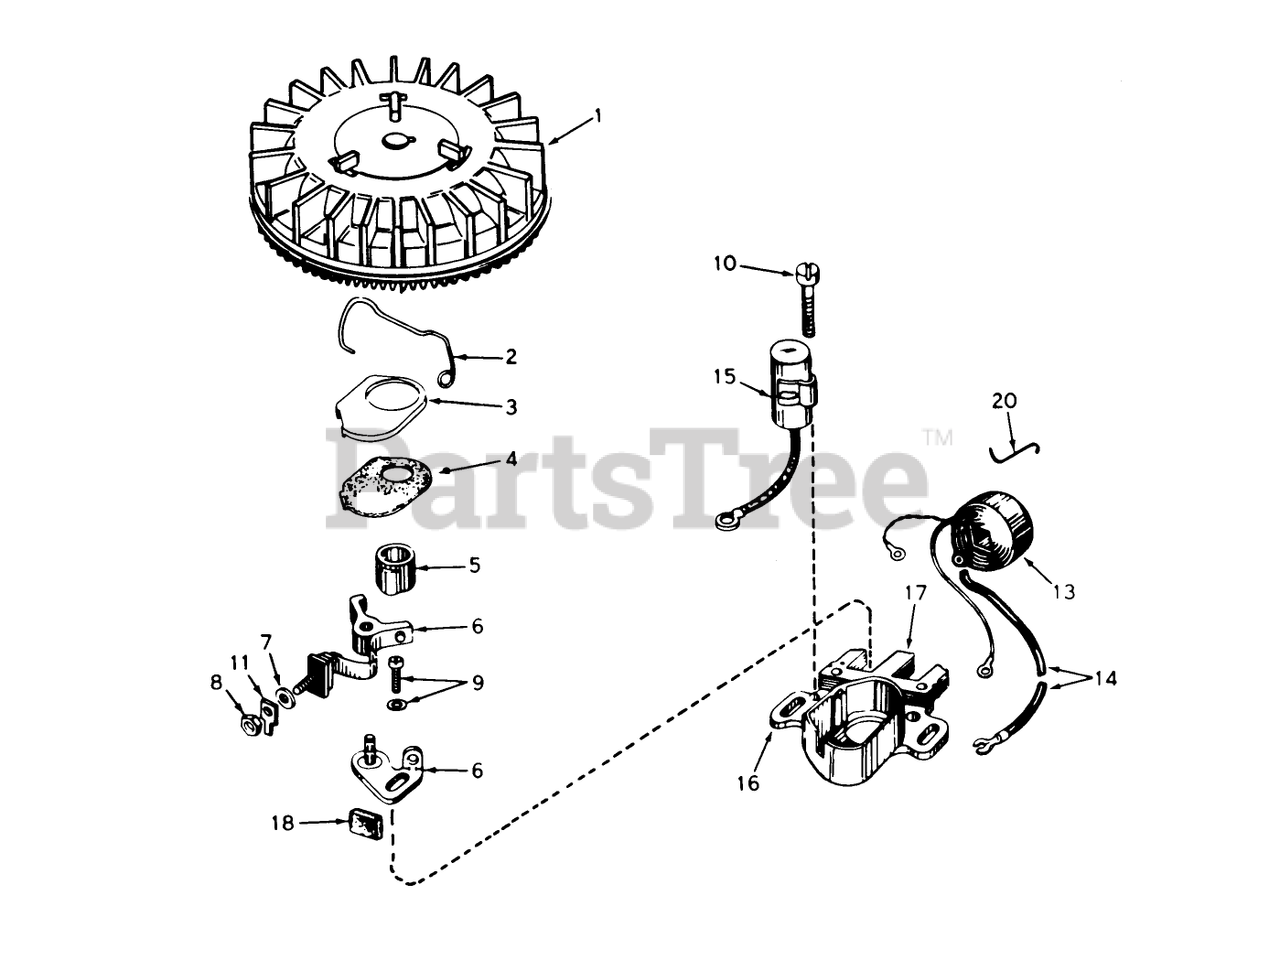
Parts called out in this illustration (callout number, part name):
1	Flywheel
2	Spring Breaker Box
3	Cover-Dust
4	Gasket, Dust Cover
5	Cam-Breaker
6	Breaker Assy.
7	Washer
8	DECAL
9	Breaker Screw
10	Condenser Screw
11	Terminal, Ground
13	Coil Assy. (Incl. Ref. #14)
14	Wire, Lead
15	Condenser
16	Core & Plate
17	Stator Assy. (Incl. Ref. #2, 3, 4, 6 thru 16, 18 & 20)
18	Felt,Cam Wiper
20	Clip, Coil
